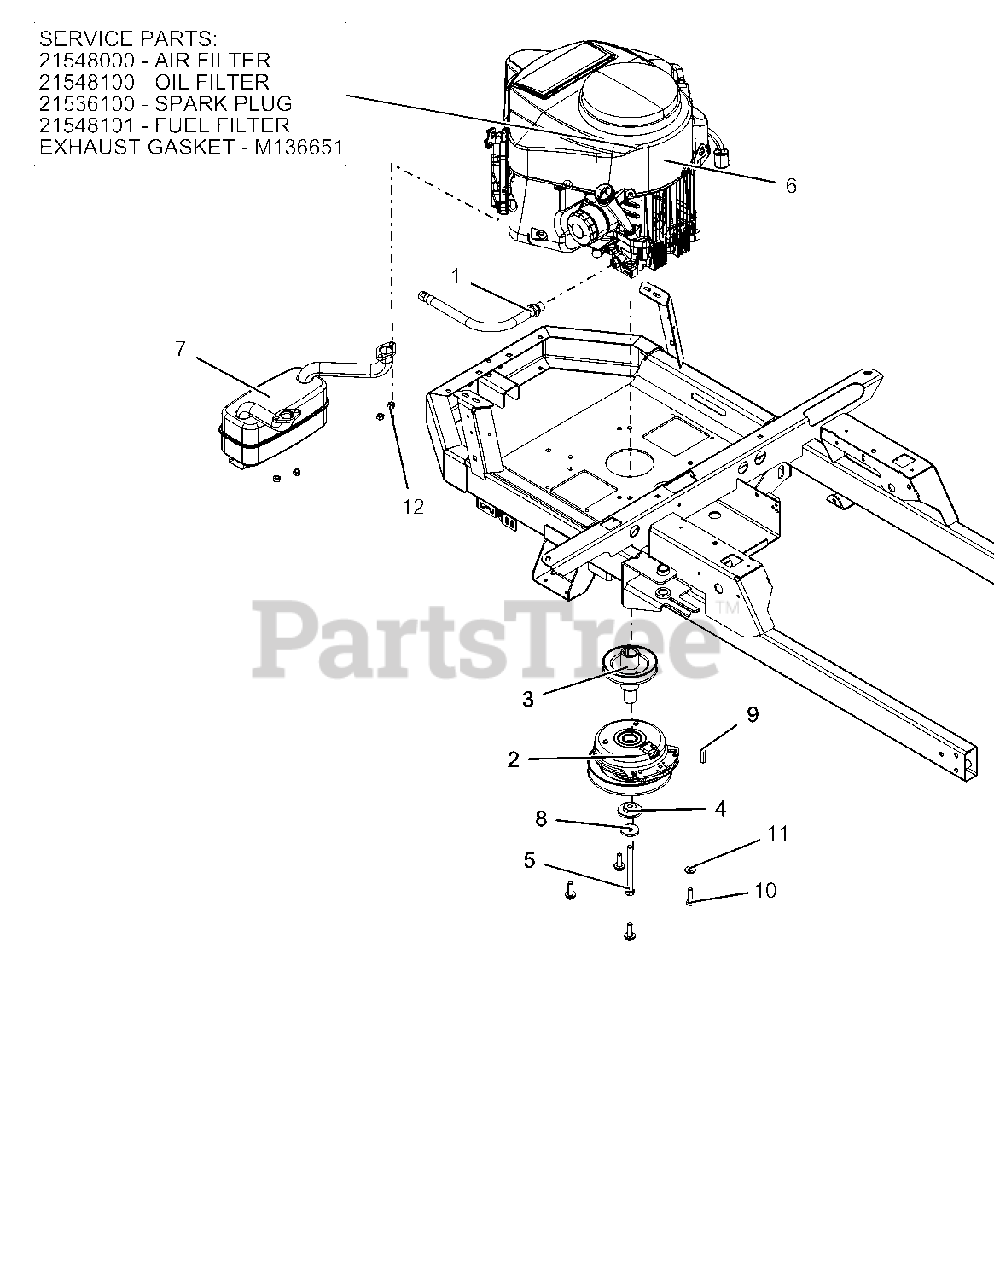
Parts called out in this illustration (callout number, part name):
1	HOSE, OIL DRAIN
2	CLUTCH,105FTLB MONOPOLE 6.83"
3	WLDMT, DRIVE SHEAVE-X
4	BSHG-FLG .469X1.06X.574X2.0
5	BLT-HEX.438-20X4.5GR8YZ NYTORQ
6	PLUG, SPARK
6	AIR FILTER, KAWASAKI FR
6	OIL FILTER, KAWASAKI FR
6	GASKET, MUFFLER #
6	ENGINE, KAWASAKI FR691 23HP
6	FUEL FILTER-KAWASAKI FR
7	MUFFLER, KAW
8	WASHER, 7/16" SPRING DISK
9	KEY-SQ .25 X 1.25 X .25 SAE
10	BLT-HEX.38-16X1.25 G5YZ NYTORQ
11	WASHER, 3/8" SPRING DISC
12	NUT-LK-TOP M8-1.25 YWZC
